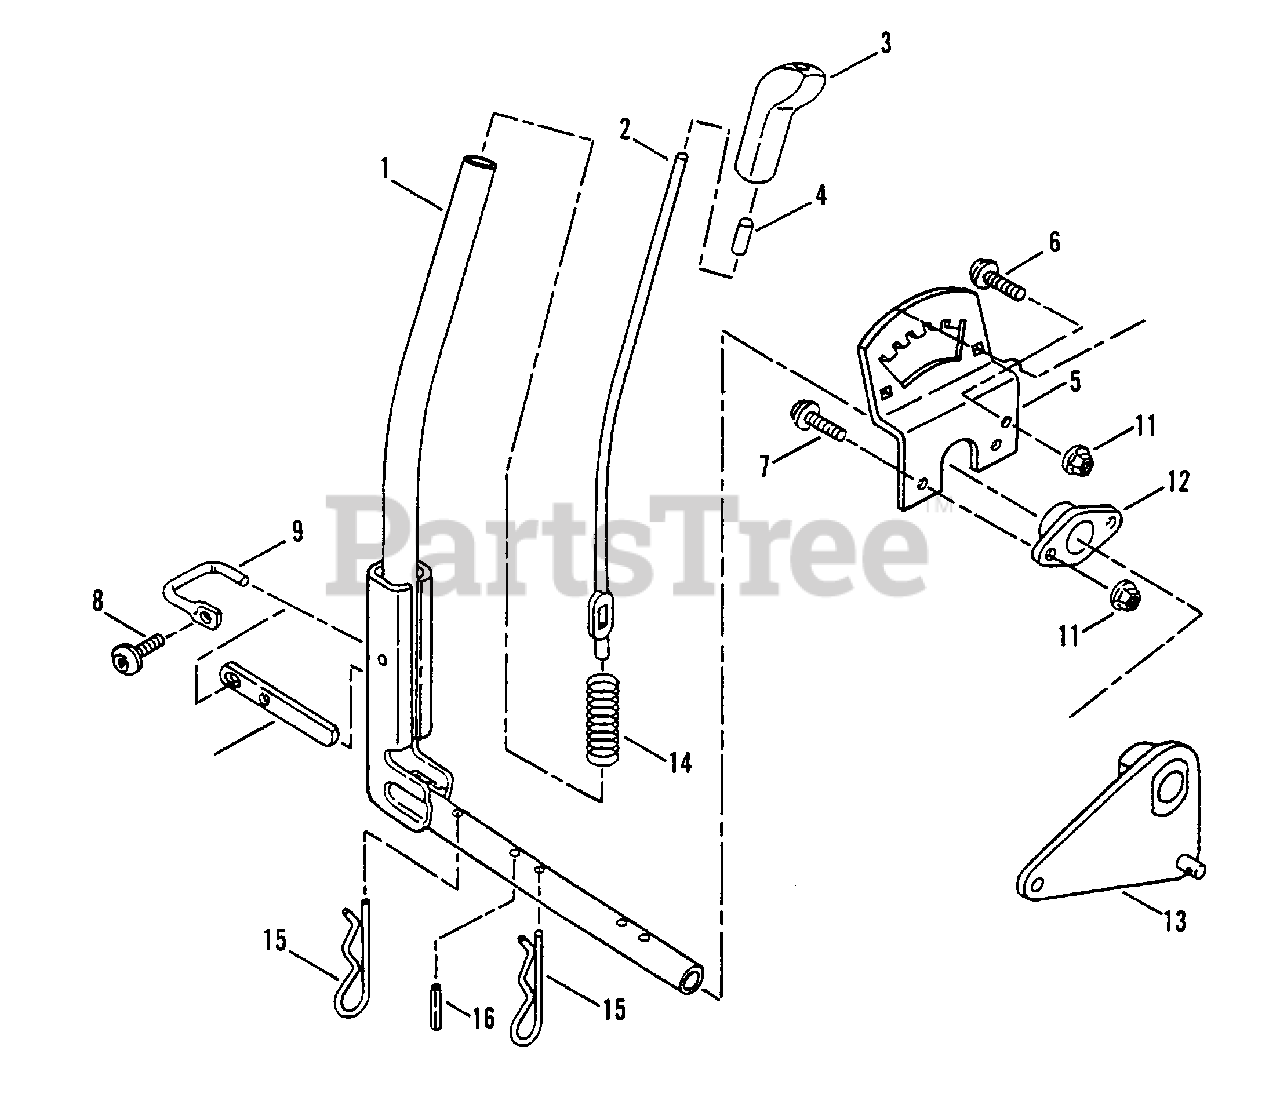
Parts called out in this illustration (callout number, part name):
1	LEVER, Implement Lift
2	ROD, Lift Lever
3	KNOB, Lift Lever
4	CAP, Lift Lever Rod
5	QUADRANT, Lift Lever
6	SCREW, 5/16-18 x 5/8" Truss Head (Torx)
7	SCREW, 5/16-18 x 7/8" Truss Head (Torx)
8	SCREW, 1/4-20 x 5/8 Truss Head (Torx)
9	LATCH, Pivot
10	DETENT, Latch
11	NUT, 5/16-18 Hex Flange Lock Grade 5
12	PIVOT, Lift Lever
13	BELLCRANK, Lift Lever
14	SPRING, Latch Detent
15	PIN, Hair, 5/32 x 2-5/8"
16	PIN, Dowel, 1/4 x 1-1/8
